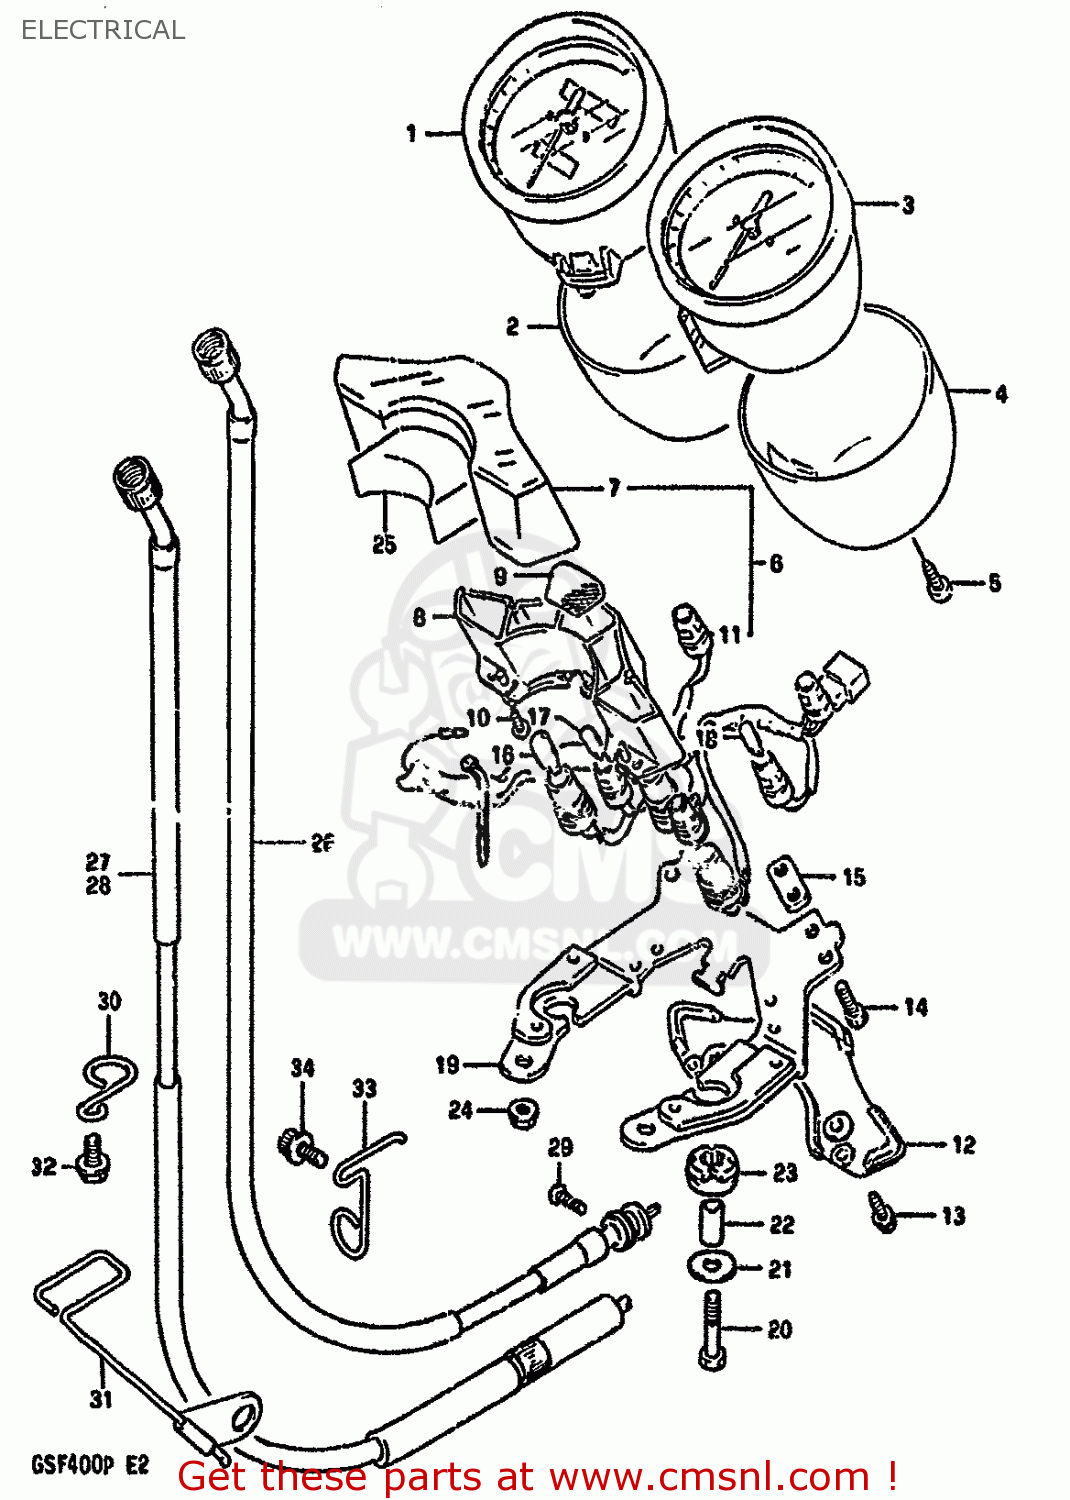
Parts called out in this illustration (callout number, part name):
1	RELAY ASSY,STARTING MOTOR
2	SCREW(6X10)
3	NUT
4	WIRE,STARTER MOTOR LEAD
5	CAP,STARTER MOTOR TERMINAL
6	CAP,STARTER RELAY
7	RECTIFIER ASSY
8	SCREW
9	BRACKET,RECTIFIER
10	BOLT
11	PROTECTOR(12X40)
12	COIL ASSEMBLY,IGNITION
13	COIL ASSY,IGNITION 2-3
14	BOLT
15	SPACER(6.2X12X16)
16	CAP,SPARK PLUG
17	SEAL,SPARK PLUG
18	SEAL,HIGH TENSION CORD
19	COVER,SPARK PLUG CAP
20	CLAMP
